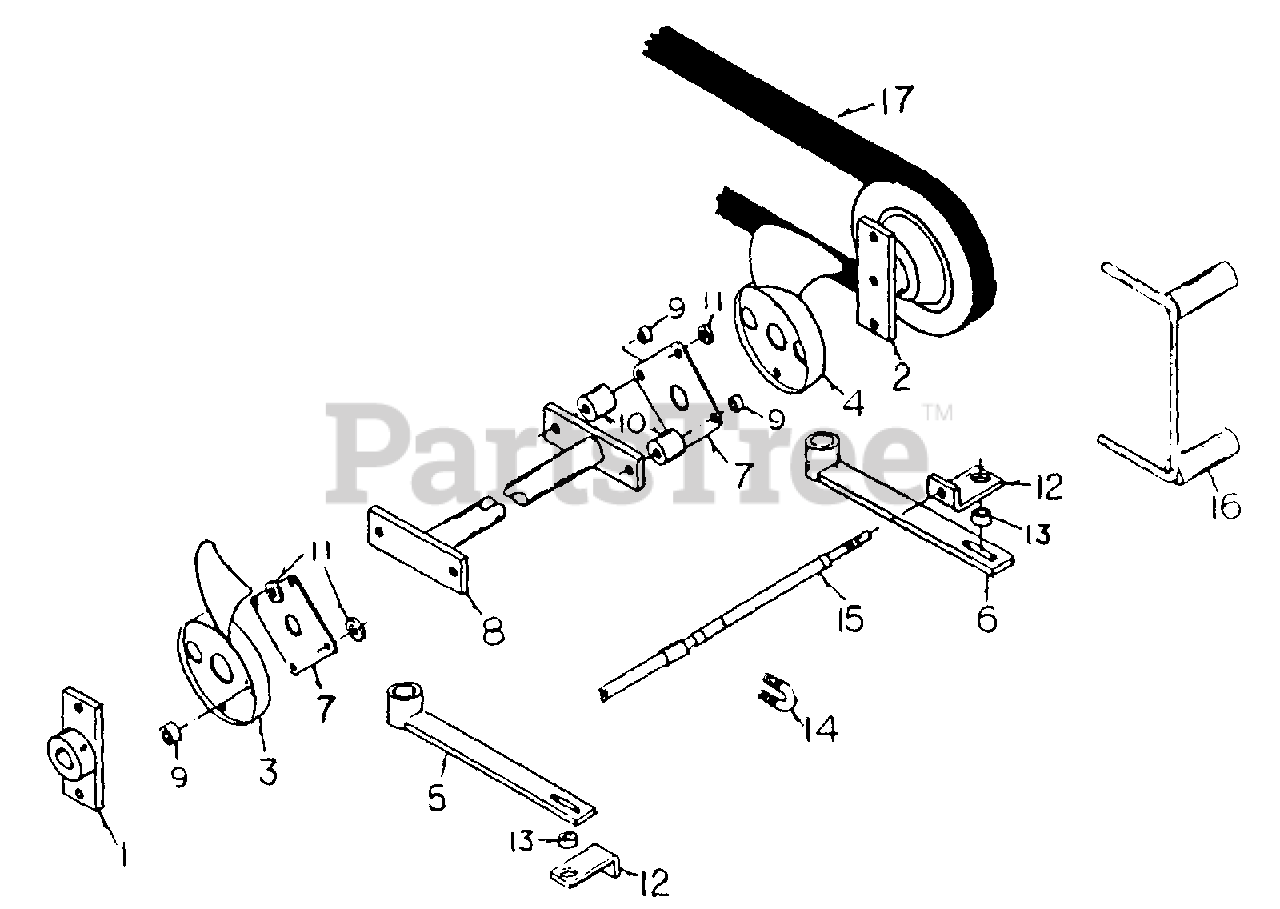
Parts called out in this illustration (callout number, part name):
1	Hub w/drive plate
2	PULLEY w/drive plate
5	TRANSMISSION ARM - L.H.
6	TRANSMISSION ARM - R.H.
7	DRIVE PLATE
8	TRANSMISSION CROSS SHAFT
11	WASHER - 1/4" 10 ga.
12	STEERING CABLE END
13	BUSHING - steering lever
14	STEERING CABLE CLAMP
15	STEERING CABLE
16	BELT RETAINER - Transmission
